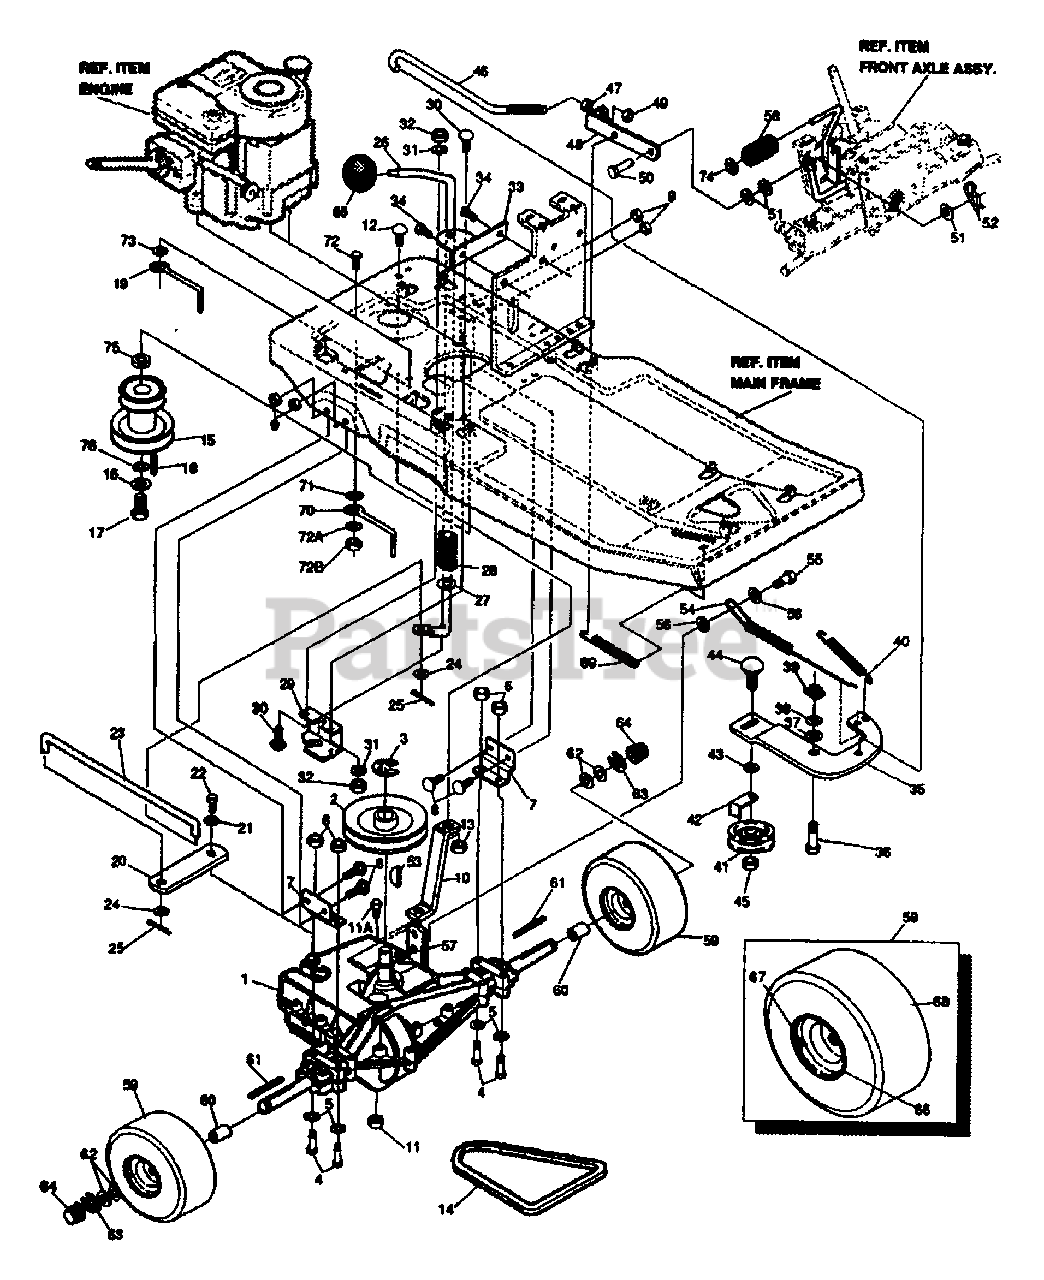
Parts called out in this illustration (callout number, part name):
1	Transaxle
2	Pulley, Transaxle
3	Ring, RETEX .58 x .04 TRU 5100-62
4	Screw, 5/16-18 x 2.50 HHC GR2
5	Washer, Flat .344 x .69 x .065
6	Nut, 5/16-18 REG HEX CTR LK
7	Bracket, Transaxle
8	Bolt, 5/16-18 x .63 CARR
9	Nut, 5/18-18 REG HEX CTR LK
10	Bracket, Transaxle Support
11	NUT, 5/16-18 REG HX CTR LK
11A	SCREW,5/16-18 X 2.000
12	Bolt. 5/16-18 x .63 CARR
13	Nut, 5/16-18 REG HEX CTR LK
14	Belt, V 4L
15	Pulley. ENG 3.315 OFF/3.87 D/3.00 D
16	Washer, REG SPT LK .459 x .78 x.12
17	Screw, 7/16-20 x 2.50 HHC
18	Key, Square .250 SQ x 2.50 Lg
19	Belt Guide
20	Shift Lever, Brkt
21	Washer, .750 x .250
22	Screw. 1/4-28 x .75 NYL HH CGR8
23	Rod, Shift Connecting
24	Washer, Flat .406 x .81 x .065
25	Pin, Cotter .125 DIA X I.00 LG
26	Handle, Shift
27	Washer, Flat .531 x 1.06 x .095
28	Spring, Shift Lever
29	Bracket Detent Shift
30	Bolt, 5/15-18 x .75 CARR
31	Washer, Flat .344 x .69 x .065
32	Nut, 5/16-18 REG HEX CTR LK
33	Shift Control Brkt.
34	Screw, 1/4-20 x .50 WA HH TAP
35	Arm, Idler, Transaxle Drive
36	Bolt,.625 x .218 HH SH 5/16-18z
37	Washer, Flat .635 x 1.31 x .07
38	Washer, Flat .333 x .87 x .110
39	Tinnerman Clip
40	Spring .071 x .62 x 4.37
41	Pulley, ldler
42	Retainer, Strap Belt
43	Washer, Flat .406 x .73 x .063
44	Bolt, 3/8-16 x 1.50 CARR
45	Nut, 3/8-16 REG HX CTR LK
46	Rod Clutch
47	Nut, 5/16-18 HEX KEPS.
48	Brkt. Clutch Brake
49	Nut, 5/16-18 REG HEX CTR LK
50	Pin Clevis .312 x .812
51	Washer, Flat .3444 x .69 x .065
52	Pin, Hair .091 DIA x 1.66 LG
53	Key, Woodruff
54	Spring, Brake
55	Bolt, .500 x .375 HH SH 5/16-18
56	Washer, Flat .515 x 1.31 x .09
57	Nut, 5/16-18 REG HEX CTR LK
59	Tire & Rim, Pnuematic
61	Key, Square .187 SQ x 2.25 LG
62	Washer, Flat .755 x 1.53 x .07
63	Ring, RET EX .57 x .05 TRU 5133-75
65	Shift Knob
67	Valve Stem
68	Tire 16 x 6.50 - 8 Turf
69	Spring, 536 OD x .047 x 3.4
70	Belt Guide
71	Washer. Exlk .384 X .69 X .04
72	Screw, 5/16-18 X 1.000
72A	Washer, Flat .406 x .81 X .065
72B	Nut, 5/16-18 X .75
73	Washer, EX LK .384 x .69 x .04
74	Cap, Push Nut
75	Spacer, Engine Sheave
76	Washer, .980 ID X 1.380 OD X .437 Pilot
